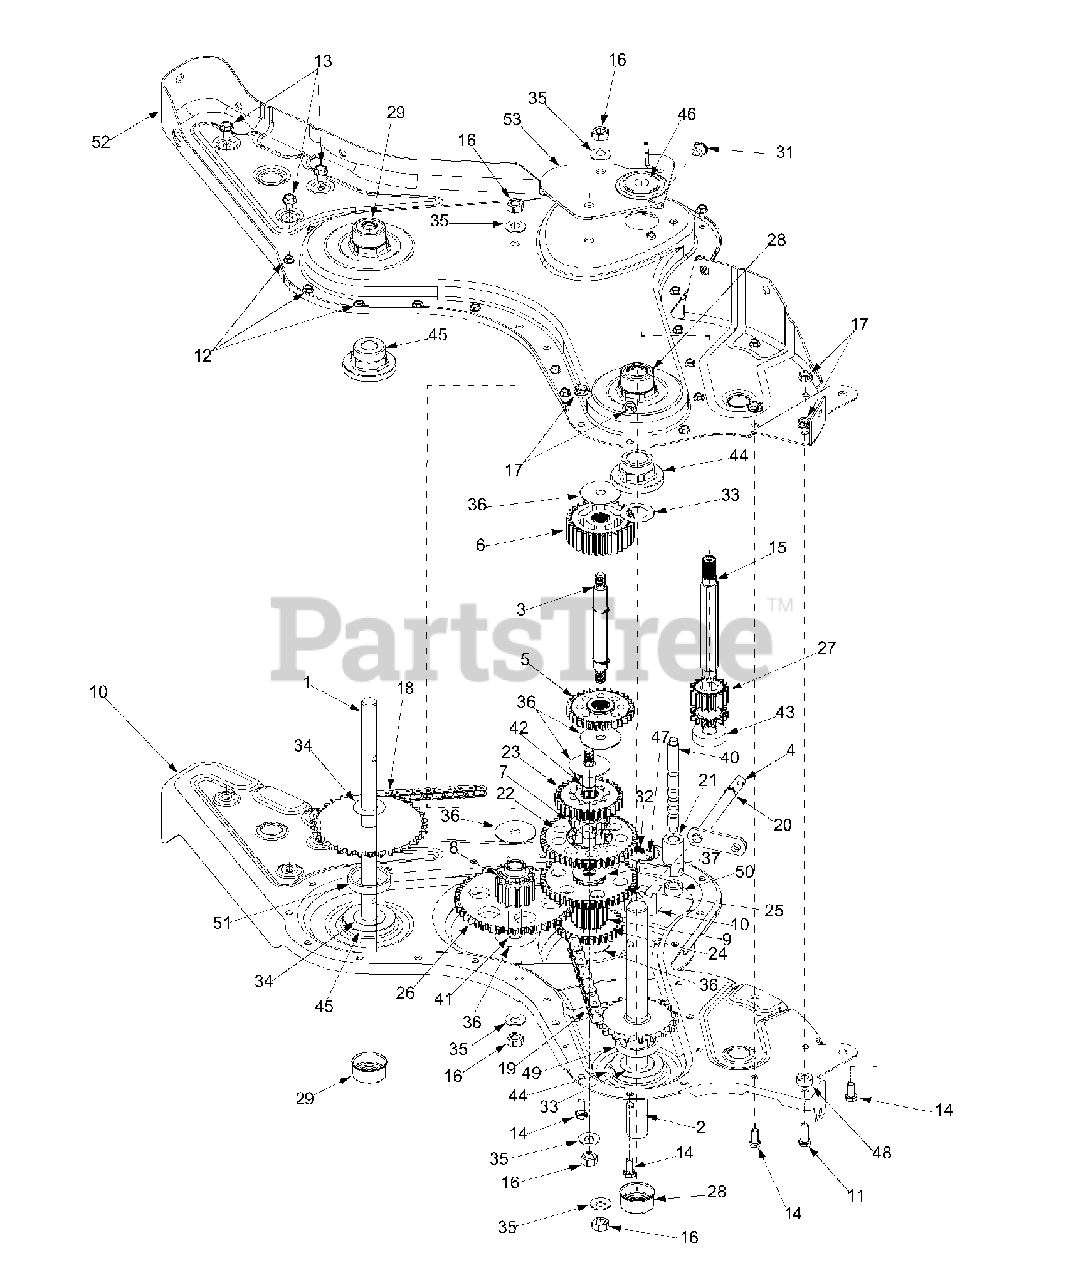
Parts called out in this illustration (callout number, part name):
1	Wheel Shaft Ass'y 33T
2	Tine Shaft Ass'y: 18T
3	Jack Shaft Ass'y
4	Input Shaft Ass'y
5	Rev. Idler Gear Ass'y: 30T
6	Ftine Idler Gear Ass'y: 30T
7	Tine Input Sprocket Ass'y: 9T
8	Wheel Input Sprocket Ass'y: 10T
9	Gear Ass'y: 11T
11	Hex Bolt 5/16-18 x 1" Lg.
12	Hex S-Tap Scr. 1/4- 20 x .5"
13	Hex S-Tap Scr. 5/16-18 x .625"
14	Hex Bolt 5/16-18 x .75"
15	Input Shaft
16	Hex Nut 7/16-20
17	Flange Nut 5/16-18
18	#420 Chain 1/2 Pitch x 50 Links
19	#50 Chain 5/8 Pitch x 54 Links
20	Snap Ring
21	Shifting Fork
22	Spur Gear 44T
23	Spur Gear 30T
24	Spur Gear 30T
25	Spur Gear 44T
26	Spur Gear 44T
27	Spur Gear 16T
28	Seal 1.0 Shaft
29	Seal .75 Shaft
31	Taper Cap Ring
32	Compression Spring .50" Lg.
33	Thrust Wash. 1.03" I.D. x 1.62"
34	Fl-Wash .76" I.D. x 1.5" O.D.
35	Bell-Wash .45" I.D. x 1.0"
36	Thrust Wash. .445 x 1.92 x .060
37	Fl-Wash. .635" I.D. x 1.59 O.D.
40	Detent Shaft 1/2" Dia.
41	Jack Shaft .625 x 2.385
42	Jack Shaft .625 x 5.0
43	Ball Bearing
44	Flange Bearing 1.0 x 2.5 x 1.38
45	Flange Bearing .75 x 2.5 x 1.38
46	Ball Bearing .6692 x 5745 x .466
47	Detent Ball .250
48	Spacer .315
49	Spacer 1.0 I.D x 2.0 O.D. x .440
50	Spacer .505 I.D. x .88 O.D. x .440
51	Spacer .75 x 2.0 x .50
53	Gear Positioner Bracket
